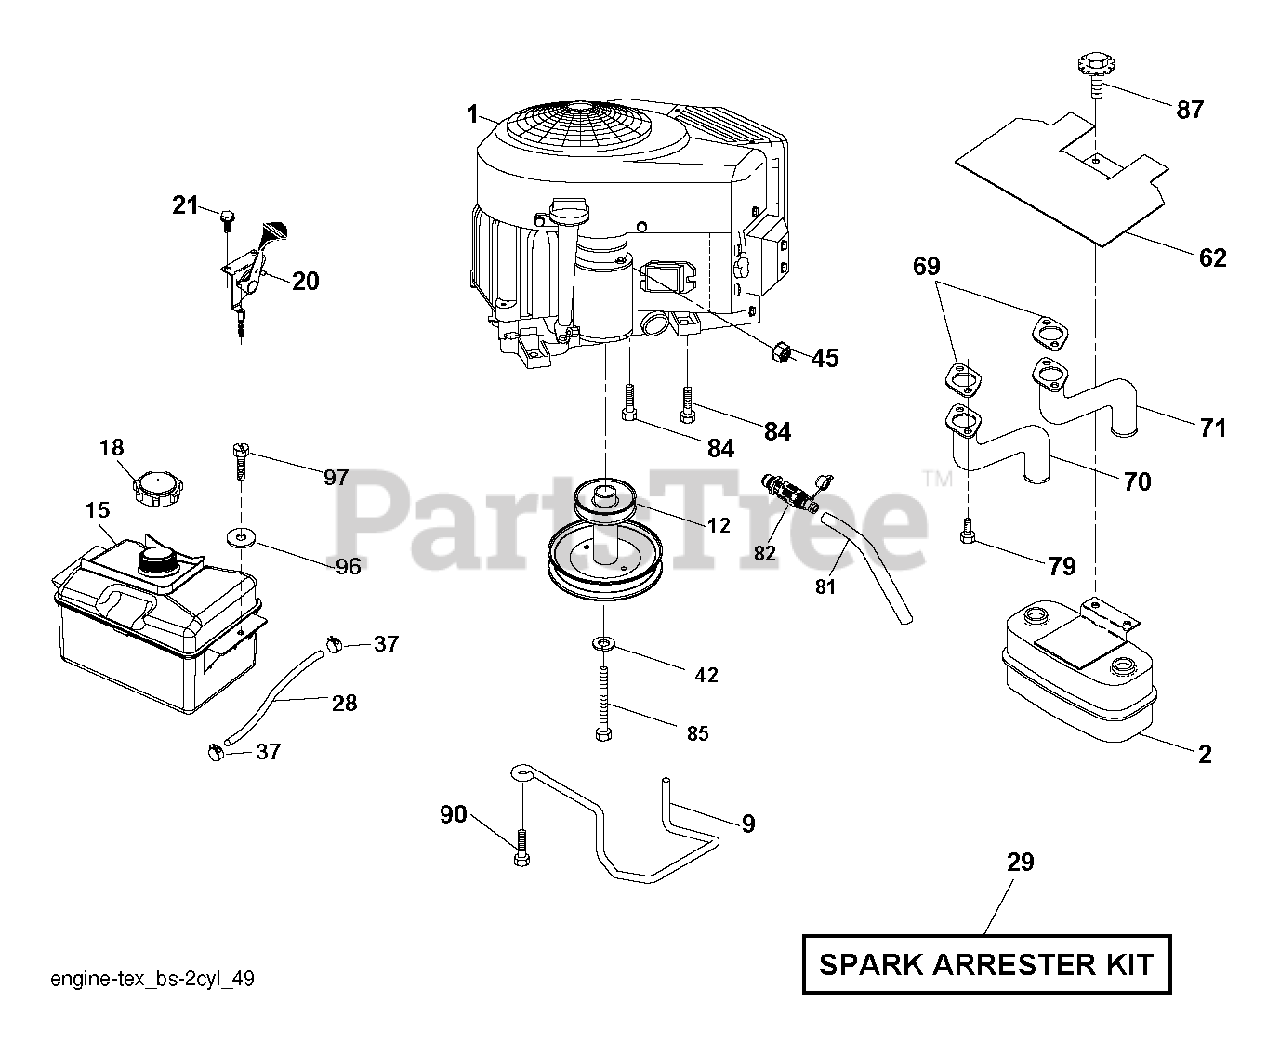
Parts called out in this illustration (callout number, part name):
2	MUFFLER.TWIN.CYL.LOW.TONE
9	KEEPER.BELT.ENGINE.4.2
12	PULLY ENGINE
15	TANK.ASM.FUEL.FR.2.5GA.
18	CAP ASM.FUEL.2.25"FR.
20	CONTROL.TH/CK.COBRA.B&S.TWN.
21	SCREW.#10 X 0.750.BOS
28	LINE.FUEL.20"FRONT.EMI
29	KIT.SPARK ARRESTOR 794945 B&S
37	HOSE CLAMP
42	LOCKWASHER
45	NUT
62	SHIELD.HEAT.MUFFLER
69	GASKET.MUFFLER
70	RP.EXHAUST.TUBE.LH.BS/TWIN
71	EXHAUST.TUBE.RH.BS/TWIN
79	SCREW.SOCKET.HEAD.5/16-18
81	TUBE, DRAIN OIL ASM.
82	VALUE.OIL.DRAIN
84	SCREW.3/8-16
85	BOLT HEX 7/16-20X4-1/4"
87	Bolt, 5/16-18 X 1-3/4
90	SCREW 3/8-16X1
96	WASHER
97	SCREW HEXWSHR 1/4-20X3/4
